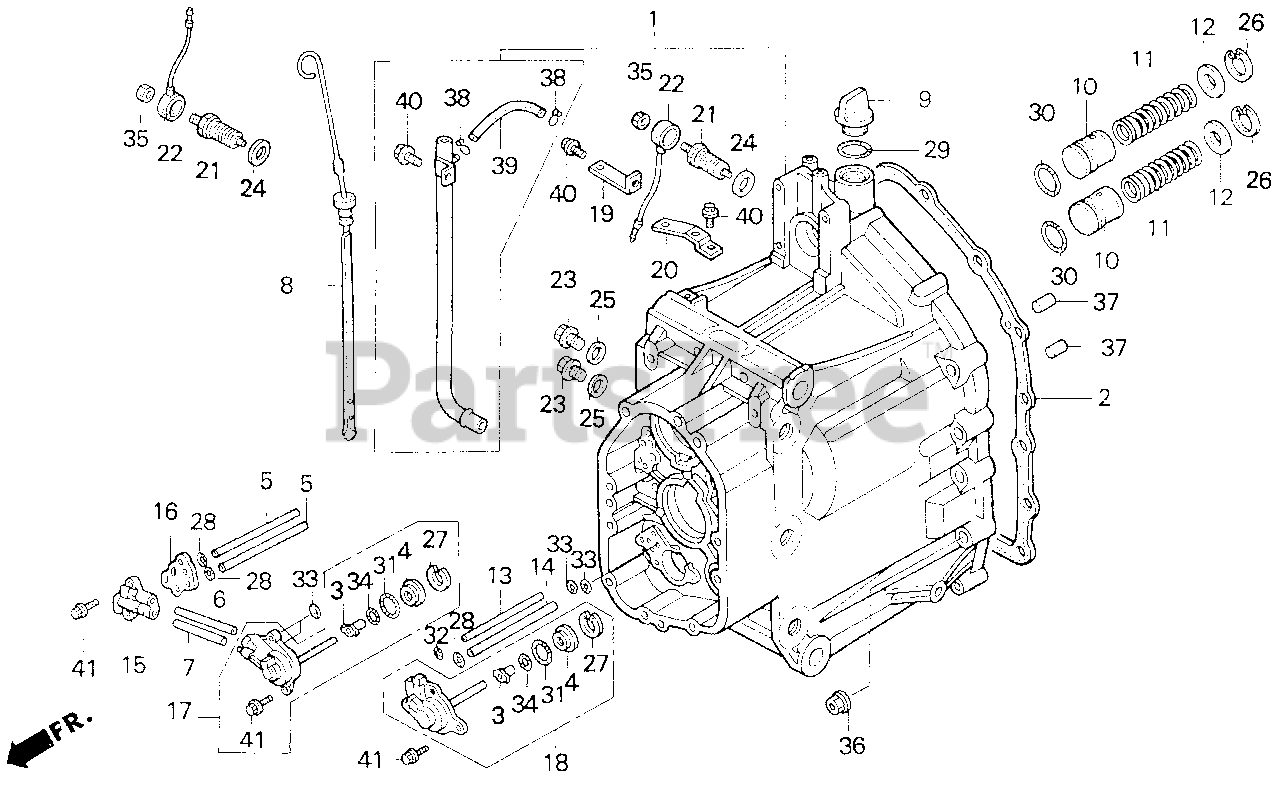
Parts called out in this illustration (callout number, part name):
1	CASE, FR. TRANSMISSION
2	GASKET, FR. CASE
3	PIPE A, FEED
4	GUIDE A, FEED PIPE
5	PIPE, CLUTCH SUPPLY
6	PIPE, SECOND CLUTCH
7	PIPE, THIRD CLUTCH
10	PISTON, LOW ACCUMULATOR
11	SPRING, ACCUMULATOR
12	COVER, ACCUMULATOR
13	PIPE, P.T.O. SUPPLY
14	PIPE, P.T.O. CLUTCH
15	HOLDER, FEED PIPE (A)
16	GASKET, FEED PIPE HOLDER
17	HOLDER ASSY. B, FEED PIPE
18	HOLDER ASSY., FEED PIPE (D)
19	BRACKET, WIRE HARNESS
20	BRACKET, WIRE HARNESS CLIP (C)
21	SWITCH, REVERSE (TOYO)
22	WIRE, NEUTRAL SWITCH
23	BOLT, SEALING (8MM)
24	WASHER, NEUTRAL SWITCH
25	WASHER (8MM)
26	CIRCLIP (INNER) (30MM)
27	CIRCLIP (INNER) (38MM)
28	O-RING (7.7X2.3) (ARAI)
29	O-RING (22X3.0)
30	O-RING (22.5X2.7)
31	O-RING (34X1.9) (ARAI)
32	O-RING (5.7X2.2) (ARAI)
33	O-RING (8.2X1.5)
34	O-RING (8.5X1.9) (NOK)
35	NUT, HEX. (4MM)
36	NUT, FLANGE (10MM)
37	PIN, DOWEL (8X14)
38	CLIP, TUBE (B10)
39	BULK HOSE, VACUUM (5.5X3000) (5.3X125)
40	BOLT, FLANGE (6X12)
41	BOLT, FLANGE (6X20)
